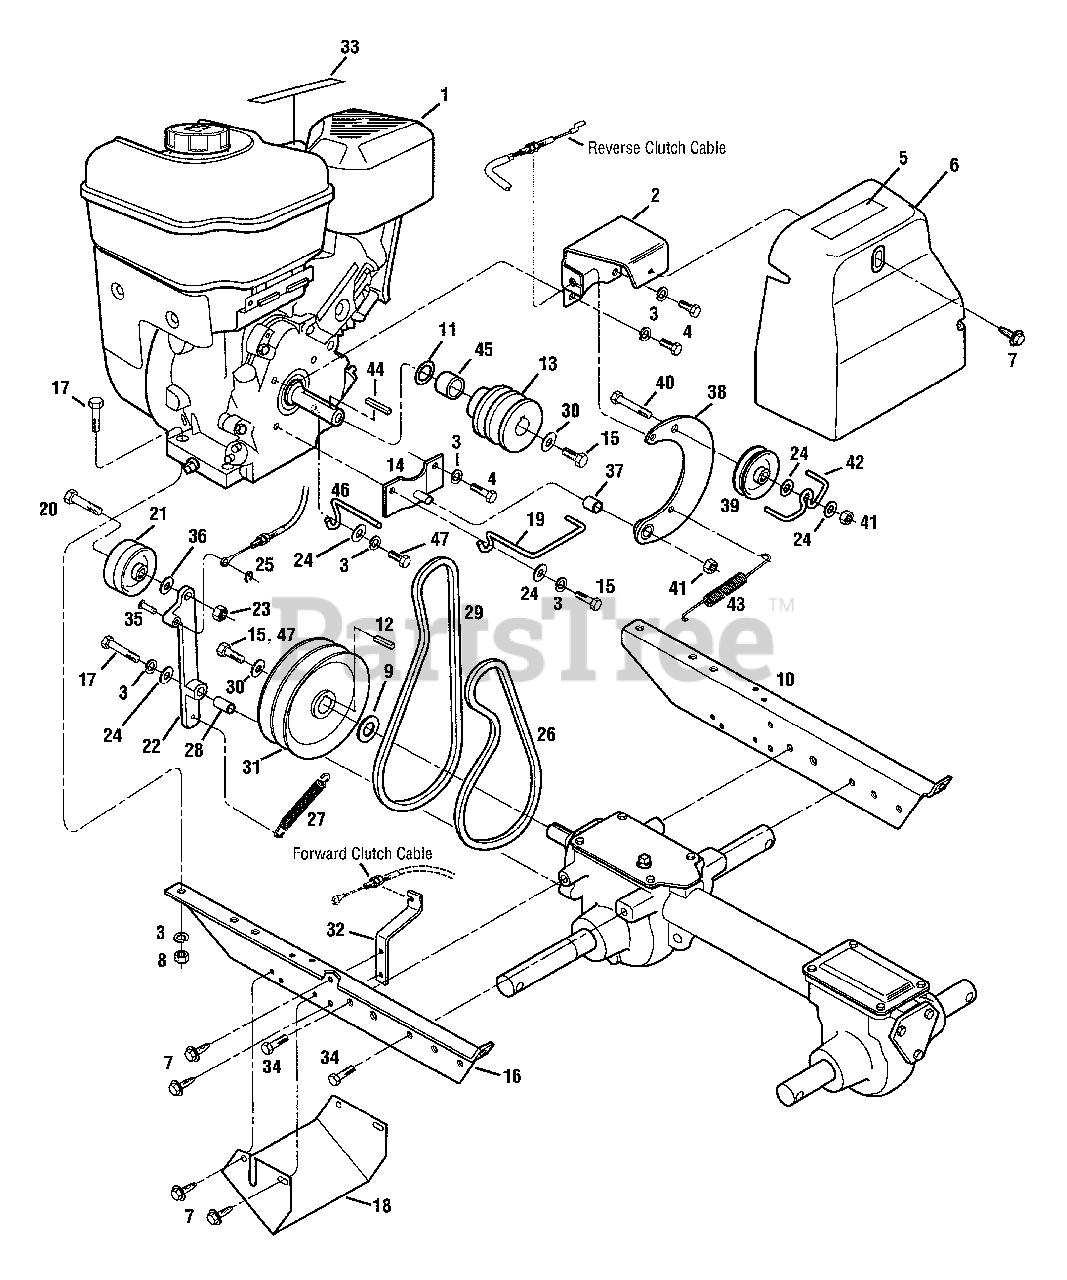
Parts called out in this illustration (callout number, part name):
1	Engine, Recoil Start
2	Bracket, Belt Cover
3	Lock Washer, 5/16
4	Hex Hd. Screw, 5/16-24 x 1/2
5	Decal, Hot Surfaces Warning
6	Belt Cover
7	Hex Hd. Flange Screw, Self-Tapping, 1/4-20 x 1/2
8	Hex Nut, 5/16-18
9	Support Washer
10	Engine Bracket, Right
11	Shim
12	Key, 3/16" x 1"
13	Pulley, Engine Drive
14	Reverse Idler Bracket
15	Hex Hd. Screw, 5/16-24 x 1
16	Engine Bracket, Left
17	Hex Hd. Screw, 5/16-18 x 1-1/2
18	Guard, Belts/Pulleys
19	Forward Belt Guide
20	Hex Hd. Screw, 3/8-16 x 1-1/2
21	Forward Idler Pulley
22	Forward Idler Lever
23	Lock Nut, 3/8-16
24	Flat Washer
25	Up Ring
26	Forward Drive Belt
27	Forward Return Spring
28	Bushing, Forward Idler Lever
29	Reverse Drive Belt
30	Belleville Washer
31	Transmission Pulley
32	Bracket, Cable Mounting
33	Decal, Stabilization
34	Hex Hd. Screw, 5/16-18 x 5/8
35	Clevis Pin
36	Flat Washer, 3/8
37	Bushing
38	Reverse Idler Arm
39	Pulley, Reverse Idler
40	Hex Hd. Screw, 5/16-18 x 2
41	Lock Nut, 5/16-18
42	Belt Guide
43	Reverse Return Spring
44	Key, 3/16" x 1-1/2"
45	Spacer
46	Forward Belt Guide
47	Hex Hd. Screw, 5/16-24 x 3/4
